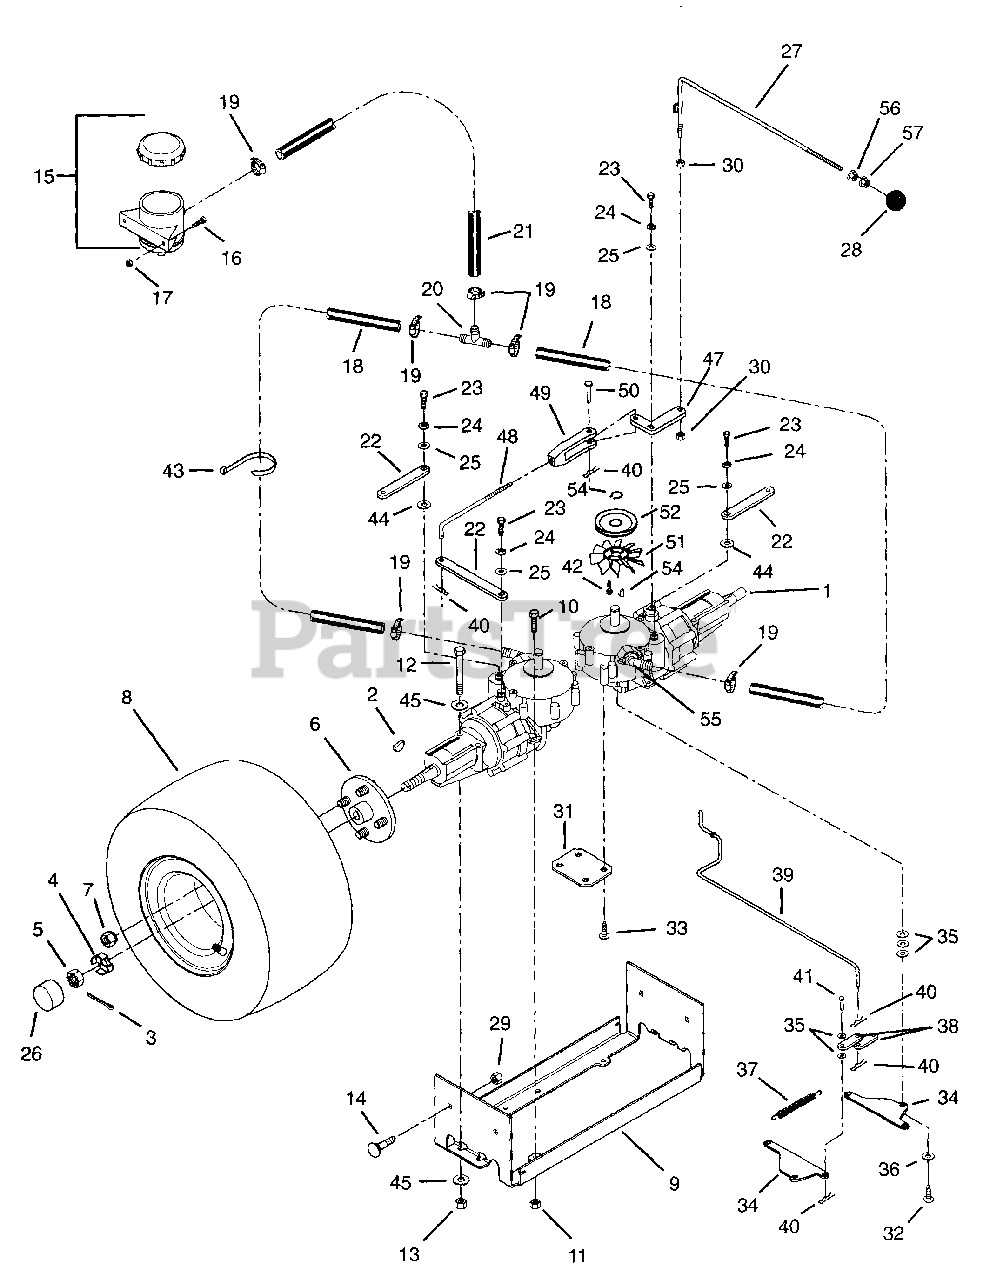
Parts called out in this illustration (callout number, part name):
1	RIGHT ANGLE TRANSAXLE
2	KEY-WDRF .25X1.00X.438 SAE15
3	PIN-COTR .12X1.0 PL
4	SPINDLE CUP
5	NUT-HEX-SL .75-20
7	NUT-LUG .50-20 PL
8	T/WHL ASSY 18X8.50-8
9	BRACKET, TRANSAXLE
10	BLT-HEX .31-18X1.00 PL GR5
11	NUT-LK-NYL.312-18 PL
12	BLT-HEX .38-16X3.25 PL GR5
13	NUT-LK-NYL .375-16 PL
14	BLT-RDHDSQNK .375-16X.75 GR5PL
15	EXPANSION TANK
16	BLT-HEX .25-20X.75 PL GR5
17	NUT-LK-NYL .250-20 PL
19	CLAMP,.88 DIA. HOSE
20	FITTING - TEE 5/8 BEADED
22	CONTROL ARM, TRANS
23	BLT-HEX .25-28X.75 PL GR5
24	WSHR-LK .250X.047 LT PL
25	WSHR-FL-STL.281X.62X.065 PL
26	HUB CAP
27	BRAKE ROD WELDMENT
28	KNOB, BALL 5/16-18 X 1.5
29	NUT-LK-CTR .375-16 GR A PL
30	NUT-LK .312-18 GR A PL
31	PLATE, TRANSMISSION LINK
32	SCR-TAP .312-18X1.0 HWH PL TR
33	SCR-TAP .312-18X.75 HWH PL TR
34	PLATE, DUMP VALVE
35	WSHR-FL-STL.344X.688X.065PL
36	SPACER BUSHING .5 X .32 X .21
37	SG-TENS .062X.50X3.1 WLD4
38	LINK, DUMP VALVE
39	ROD, DUMP VALVE
40	PIN-HAIR INT .08X.18X1.18
41	PIN-CLEV .31X.75
42	SCR-TAP .250-20X.50 HXSLHDPL
43	TIE WRAP
44	WSHR-FL-STL .505X.880X.072 PL
45	WSHR-FL-STL .390X.750X.125 PL
46	WSHR-FL-STL.344X.688X.065PL
47	BRAKE ARM
48	BRAKE SHAFT
49	YOKE, .312-24 X 2.25
50	PIN-CLEV .312X.822 HDND PL
51	FAN - EATON TRANSAXLE
52	PLY - EZR TRANSAXLE
53	RG-RTNG-EXT .672X.035
54	WOODRUFF KEY
55	FITTING 45DEG ELBOW
56	NUT-FLG. .312-18 PL
57	NUT-HEX .312-18
